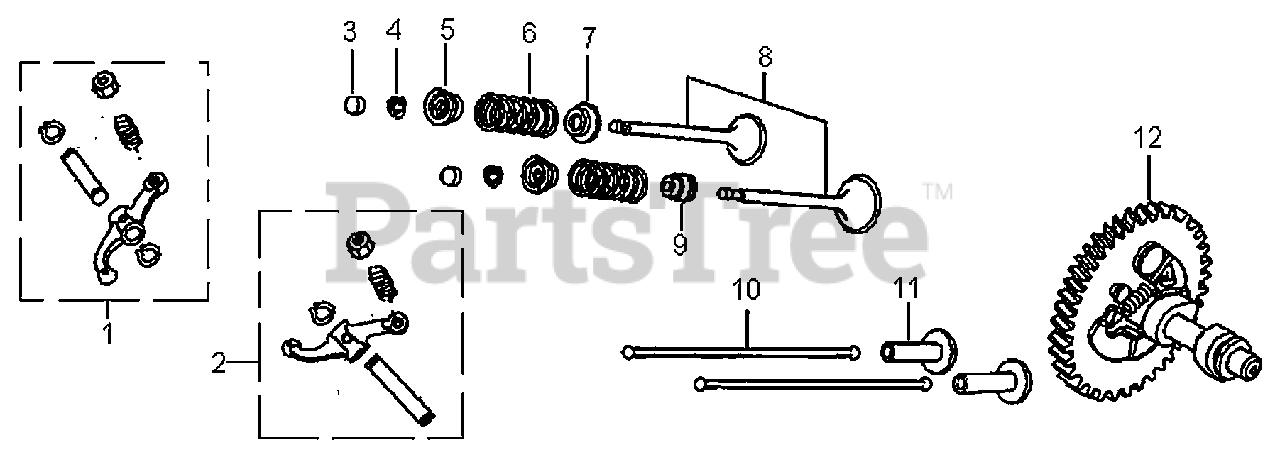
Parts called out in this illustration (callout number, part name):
1	ROCKER ARM ASSY.
2	ROCKER ARM ASSY.
3	ROTATOR,VALVE
4	VALVE LOCKER
5	RETAINER,VALVE SPRING
6	SPRING,VALVE
7	SEAT,VALVE SPRING
8	VALVE ASSY.
9	SEAL,VALVE STEM
11	LIFTER , VALVE
12	CAMSHAFT ASSY
